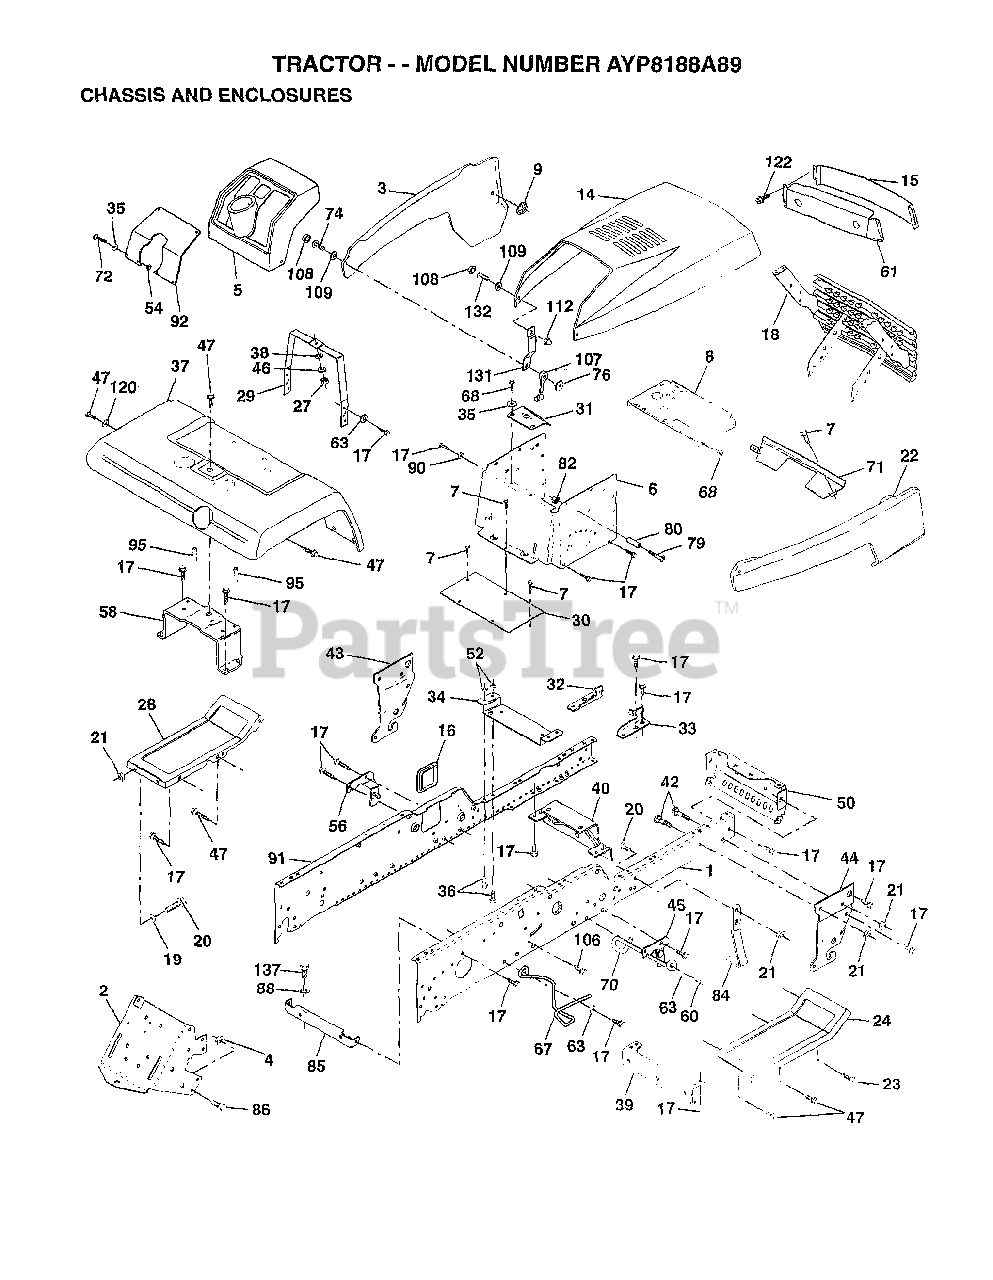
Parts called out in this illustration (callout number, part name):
1	"RAIL,FRAME RH"
2	DRAWBAR GT
3	"PANEL,ASM SIDE LH"
4	NUT.7/16
5	DASHBOARD BLACK
6	DASH LOWER
7	SCREW
8	SUPPORT.DASH.BTRY
9	PAL NUT LT
14	"HOOD ASM.,PNT"
15	LENS.BAR.CLEAR
16	COVER ACCESS
17	SCREW
19	WASHER
20	BOLT
22	PANEL ASM.SIDE RH
23	SCREW GTV
24	FOOTREST.RH.LT/GT
28	FOOTREST.LT.LT/GT
29	DASH.SUPT.YP/HUSQ
30	SADDLE.SCR.6SP
31	BRKT SUPT 1-PC VG
32	BRACKET ASM FRAME
33	BRACKET ASM FRAME
34	BRACKET.ENG.SUPT.
35	WASHER
36	BOLT
37	"FENDER,RH"
38	LOCKWASHER
39	BRACKET.AXLE.FRT.
40	"BRKT SUPPORT,AXLE"
43	BRACKET.SUS.FT.LH
44	BRACKET.SUS.FT.RH
45	BRACKET.SUSP.RH.
46	WASHER PM
47	SCREW LT
50	"BRKT CHASSIS,FRNT"
56	BRACKET.SUSP.LH.
58	BRKT.ASM.FENDER
60	SCREW
61	BEZEL.ASM.
63	WASHER
67	"GUIDE BELT, T/A"
70	GUIDE.BELT.MID.SP
72	SCREW
74	SCREW
76	WELDNUT
79	SCREW
80	SPACER LT
84	STOP.OVER.CENTER
85	BRACKET.SUPT.TRAN
86	BOLT
88	LOCKWASHER
90	LOCKWASHER
91	"BRKT ASM,GA,WH,FR"
92	"PLATE DASH,SLKSCR"
95	NUT-PUSH YT
107	HOOD LATCH T
108	SNAP CAP LT
109	WASHER LT
112	ACORN NUT RB
120	WASHER HYT
122	SCREW.HEX.WS.HD
131	BKT.SPT.HOOD/PANL
132	SCREW.10-24X3/8.
137	BOLT.FIN.HEX.
